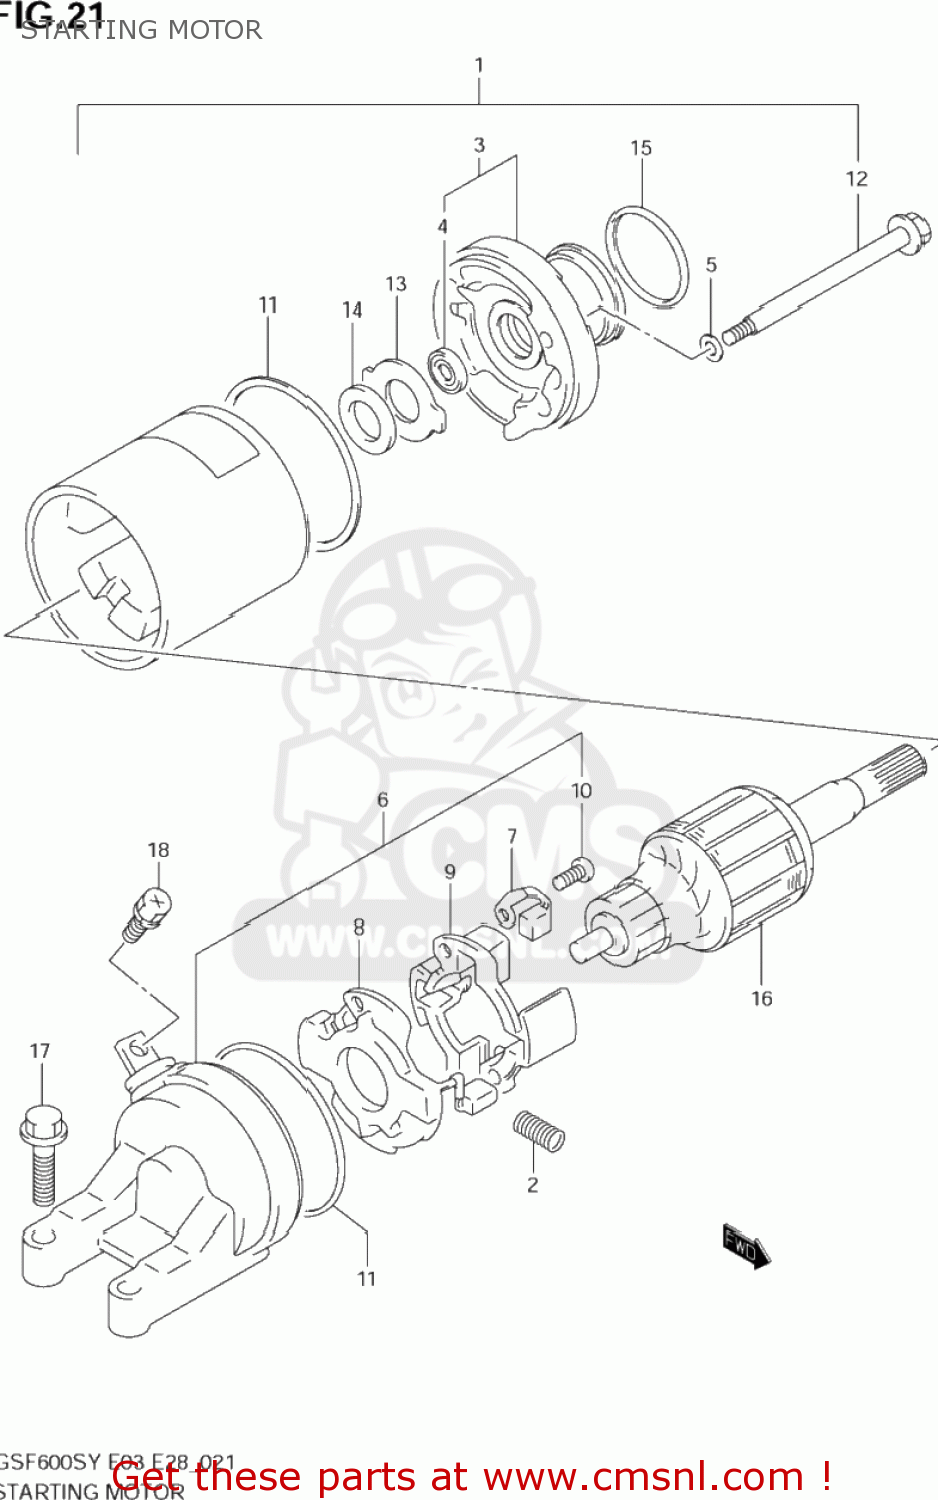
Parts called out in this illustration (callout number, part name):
1	MOTOR ASSY,STARTING
2	SPRING
3	BRACKET
4	SEAL,OIL
5	O RING
6	FRAME ASSY,COMMUTATOR
7	BRUSH
8	BRUSH SUB ASSY,STARTER
9	HOLDER,BRUSH
10	SCREW
11	O RING
12	BOLT
13	PLATE,LOCK
14	SHIM
15	O RING(D:3,ID:24.5)
16	ARMATURE
17	SCREW (6X25)
18	SCREW(5X8)
